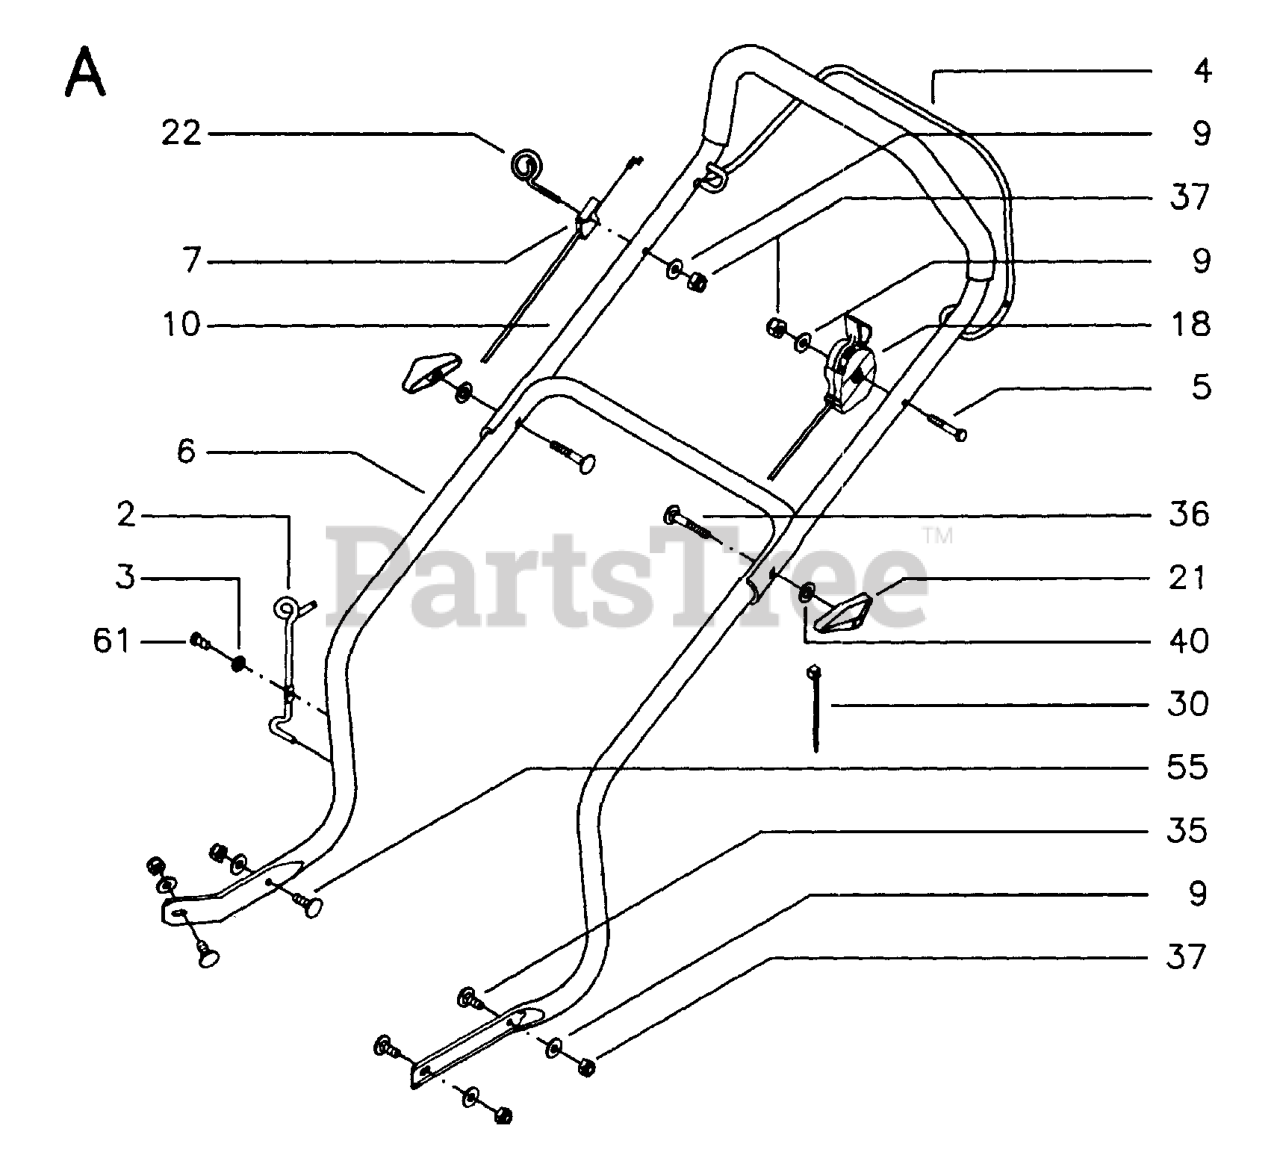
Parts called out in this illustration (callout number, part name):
18	THROTTLE TRIGGER
21	WINGNUT
37	LOCKNUT M6
40	WASHER - 15X7.3X1.6
55	REPL BY 515 71 16-20
